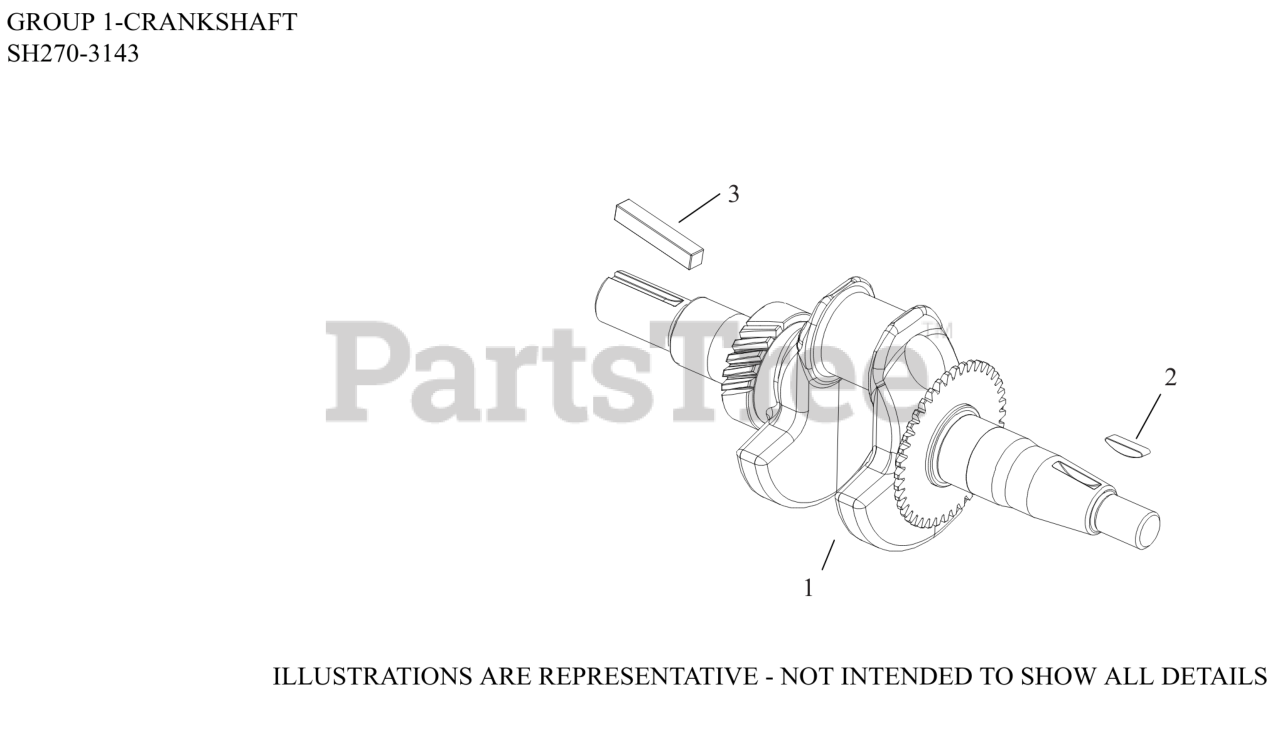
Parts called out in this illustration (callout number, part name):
1	CRANKSHAFT, ASSEMBLY
2	KEY, FLYWHEEL
3	KEY, SQUARE
